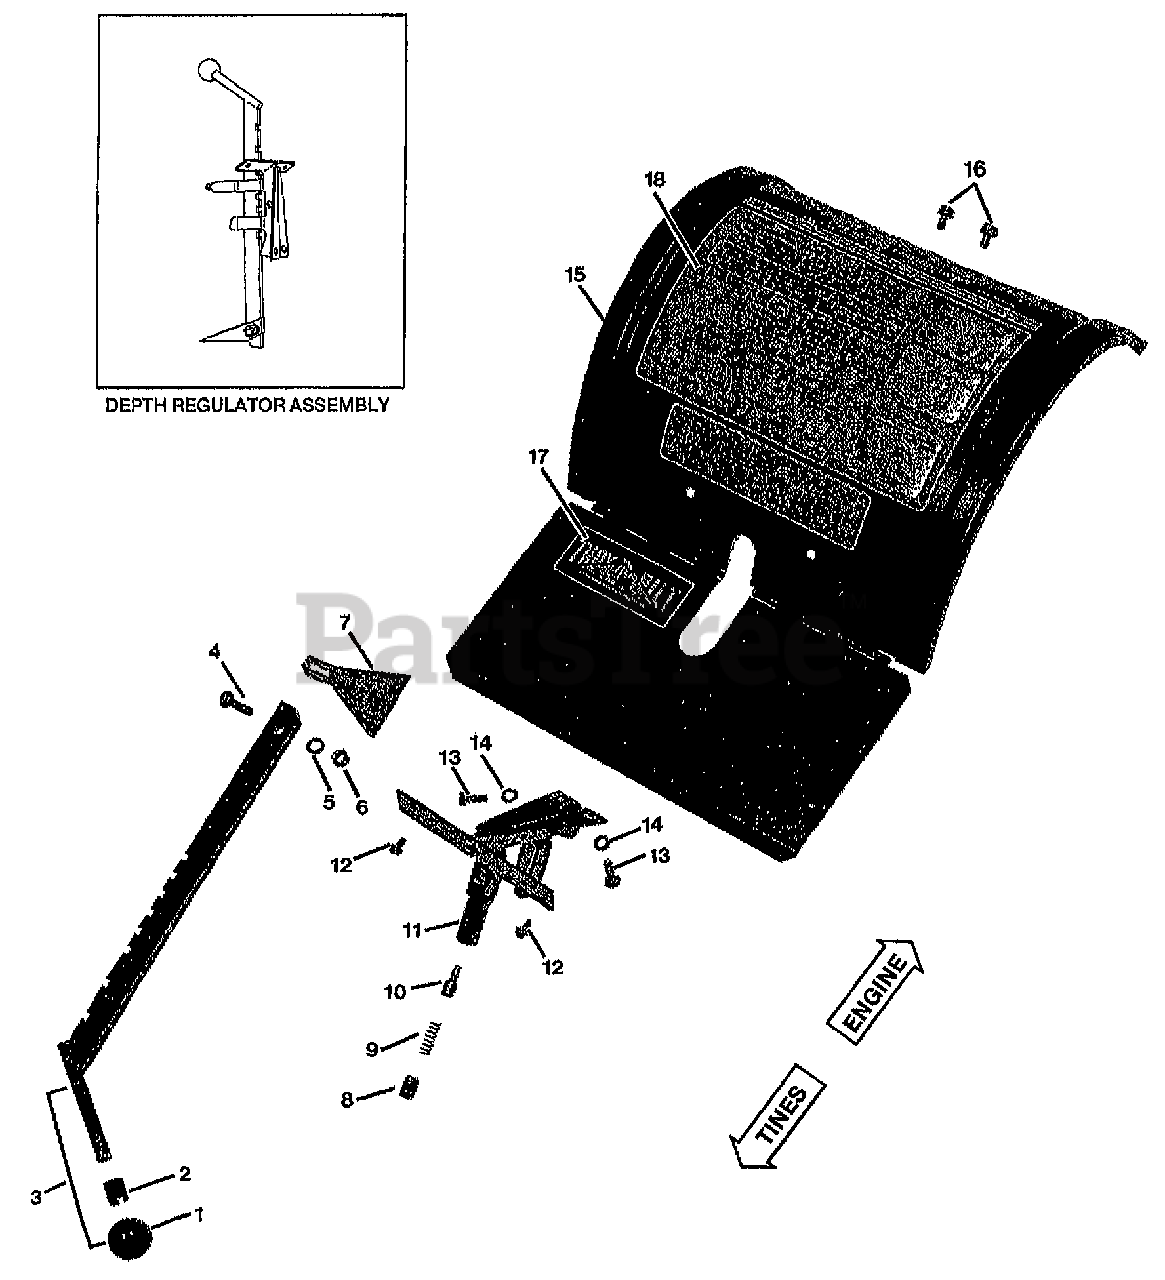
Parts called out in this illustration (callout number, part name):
1	KNOB-CONTROL (INCLUDES RETAINING RING)
2	RING-TOLERANCE .5325 ID
3	REGULATOR-DEPTH W/KNOB
4	SCR-HH 3/8-16X1.0 G5 ZP
5	WASHER-LK .375 @ DEPL
6	NUT-HEX 3/8-16 ZP
7	SHOE-DEPTH REGULATOR
8	PLUG-PIPE 1/4 NPT
9	SPRING .406 X 1.25
10	PLUNGER
11	ASSM-REAR HOOD BRKT (INCLUDES ROLL PIN)
12	SCR-HWH 1/4-20 X .5 STH
13	SCR-HHC 5/16-18X.75 GR 5 ZP
14	WASHER-LK .312 ZP
15	ASSM-HOOD W/DECALS
16	SCR-HWH 5/16-18 X .5 STH
17	DECAL-TB JR LOGO
18	DECAL-OPER INST
